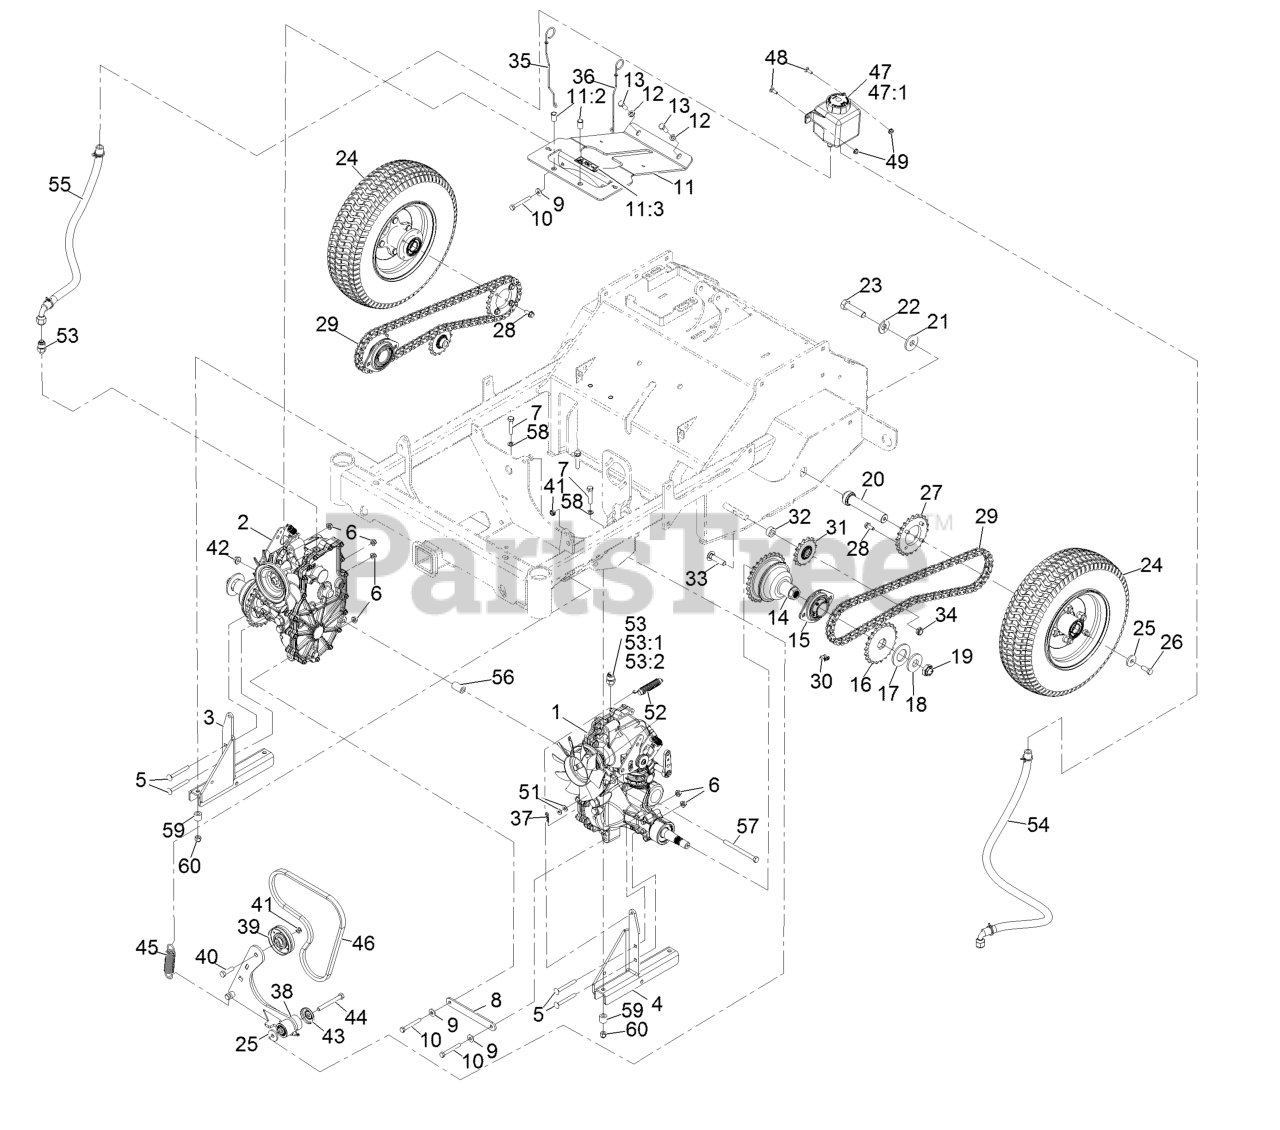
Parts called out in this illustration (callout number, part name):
1	Hydro-Zt3100, LH
2	Hydro-Zt3100, RH
3	Mount-Hydro, RH
4	Mount-Hydro, LH
5	Bolt-Carriage 5/16-18 X 2 03/04/18
6	Nut-Nyloc 5/16-18 Flg
7	Screw-HH 3/8-16 X 1 3/4
8	Crossmember-Transmission
9	Washer-Spring Disc 5/16
10	Screw-HH
11	Support-Cover
11:2	Insert-Nut
11:3	Decal-Danger
12	Washer-Lock 3/8
13	Screw-HH 3/8-16 X 1
14	Hub-Bell
15	Bearing-Flanged
16	Sprocket
17	Washer-Spacer
18	Washer-Belleville
19	Nut-Lock
20	Axle-Wheel, Drive
21	Washer-Spacer
22	Washer-Belleville
23	Screw-HH
24	Wheel And Tire ASM
25	Washer-Flat
26	Screw-HH, Lock
27	Sprocket
29	Chain-Roller
30	Link-Connecting
31	Sprocket-Idler, 15T
33	Screw-CARR
34	Nut-Nyloc 1/2-13 Thin
35	Rod-Bypass, LH
36	Rod-Bypass, RH
37	Pin-Cotter
38	Idler Arm ASM
39	Pulley-Idler
40	Screw-HH 3/8-16 X 1 3/8
41	Nut-Nyloc 3/8-16 Thin
42	Nut-Nyloc 3/8-16 Flg
43	Guard-Top
44	Screw-HH 3/8-16 X 3-1/4
45	Spring-Extension
46	Belt-V, Cogged
47	Tank-HYD
47:1	Cap-Reservoir, HYD
48	Bolt-Carriage 1/4-20 X 3/4
49	Nut-Nyloc 1/4-20 Flg
52	Spring-Extension
53	Fitting-Straight
53:1	O-Ring
53:2	O-Ring-37 Flare #8
54	Hose ASM
55	Hose ASM
57	Screw-HH 3/8-16 X 4-1/2
58	Spacer-Brake, Parking
60	Nut-Lock
